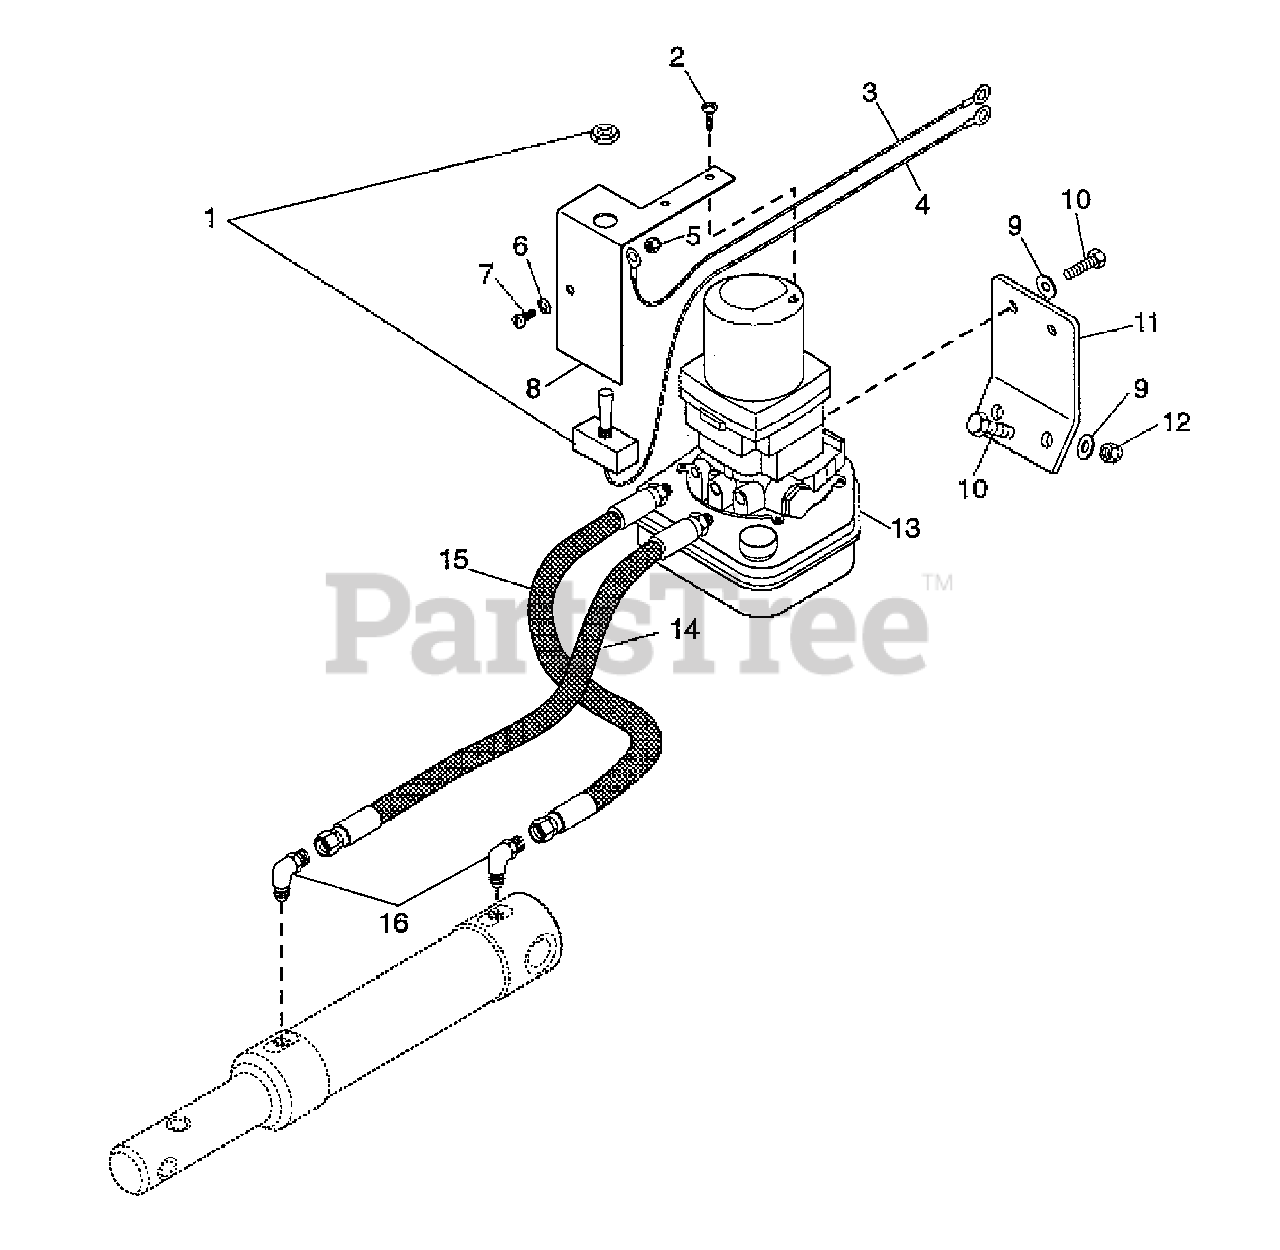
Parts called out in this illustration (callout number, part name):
1	Switch Assembly
2	Screw-Tapping 12-14 x .50
3	Ground Wire Deck Lift Pump
4	Power Wire, Deck Lift Pump
5	Nut-Locking-Nylon .250-20 Grade 2
6	Washer-Flat-Steel .281 x .625 x .065
7	Screw-Machine .25-20
8	Dash End Plate/Pump Bracket - Deck Lift
9	Washer-Flat-Steel .406 x .812 x .065
10	Bolt-Hex .38-16 x .75 Grade 5
11	Lift Pump Mounting Bracket
12	Nut-Locking-Nylon .375-16
13	Pump, Electric-Hydraulic
14	Assembly, Hose Pump to Cylinder
15	Hose, Hydraulic, Deck Lift, .25 x 36
16	Adapter 2503-4-4
